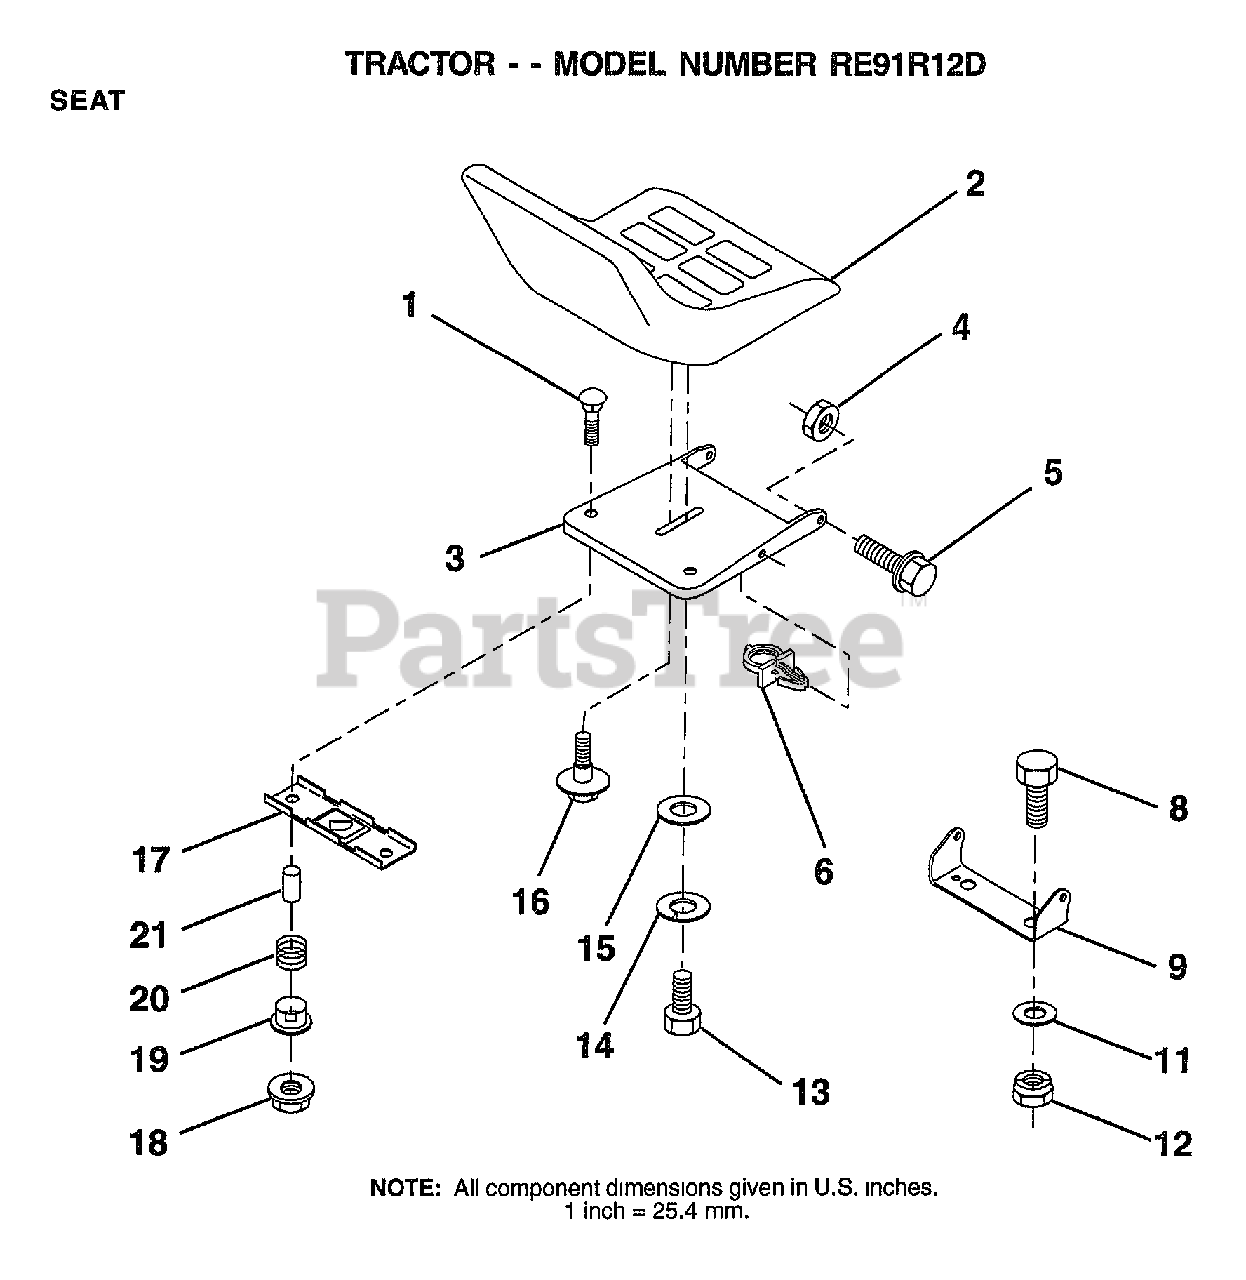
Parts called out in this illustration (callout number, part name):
1	BOLT-RD HD SQ NK
3	PAN-SEAT
4	NUT
5	"BOLT,SHOULDER"
6	CLIP.PUSH-IN.HING
8	BOLT
9	BRACKET PVT SEAT
11	WASHER
12	NUT
13	BOLT
14	LOCKWASHER
15	WASHER
16	"BOLT,SHOULDER"
17	BRKT SWITCH
19	BUSHING
20	SPRING
21	SPLIT SPACER
